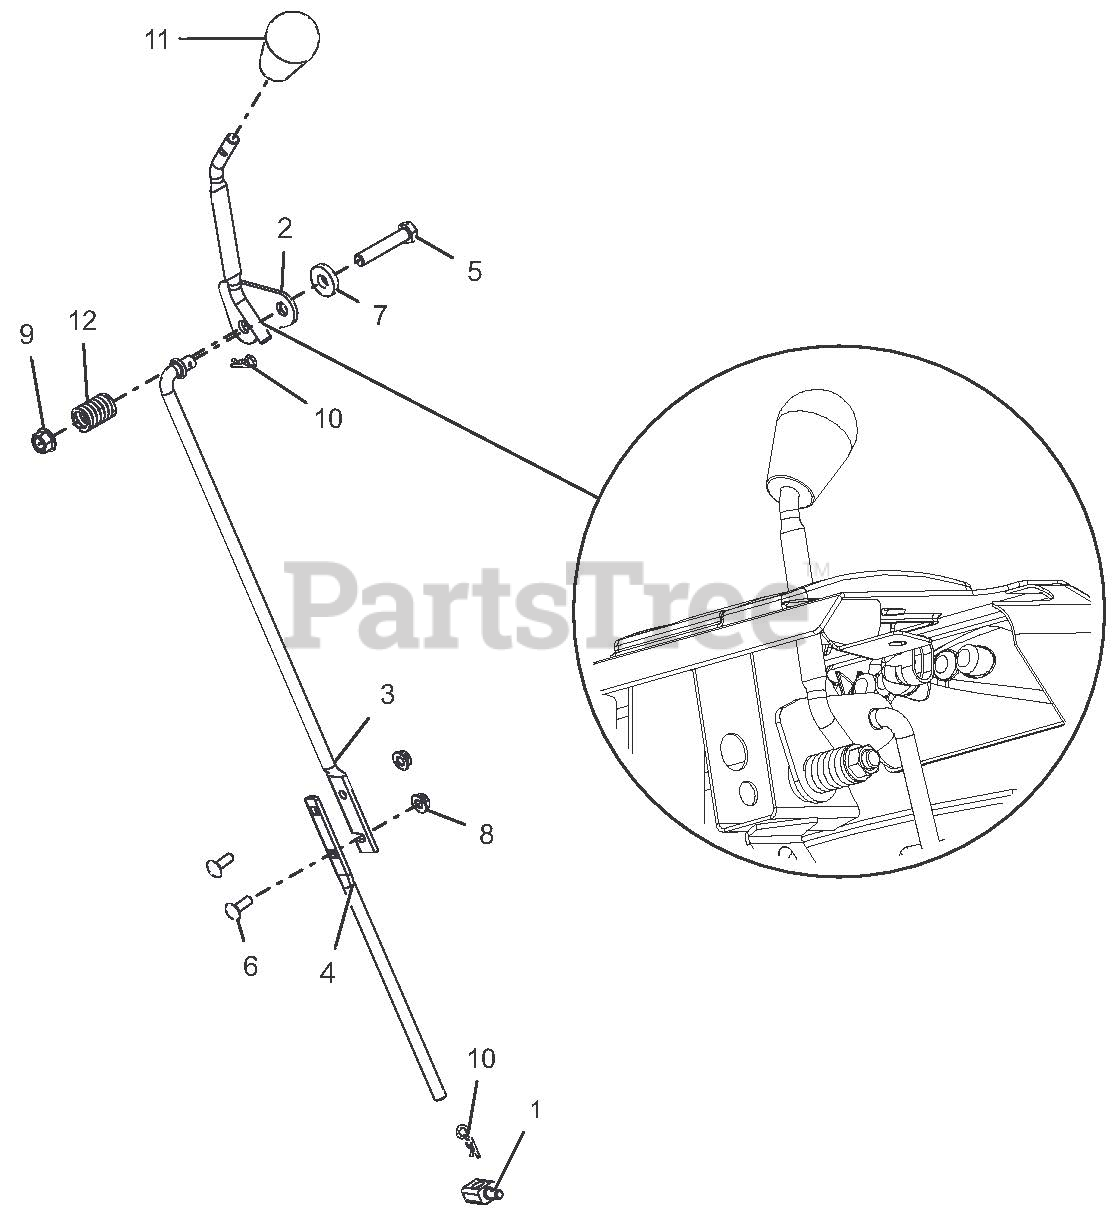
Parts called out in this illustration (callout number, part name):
1	PIVOT,SHIFT ROD .375-16(TRUNN)
2	WELDMENT, CONTROL LEVER(SHIFT)
3	ROD, SHIFT - UPPER
4	ROD, SHIFT - LOWER
5	@BLT-HEX .38-16X2.00 GR5 YWZC
6	@BLT-RDHDSQNK .25-20X.75 G5YZ
7	WSHR-FL-STL .406X1.00X.188 YWZ
8	@NUT-LK-CTR-FLG .25-20 YWZC
9	@NUT-LK-TOP-FLG .38-16 YWZC
10	PIN-HAIR INT .08X.18X1.18 YWZC
11	KNOB,SOFT TEARDROP,PUSH-ON GRY
12	SG-COMP .125X.781X1.250
